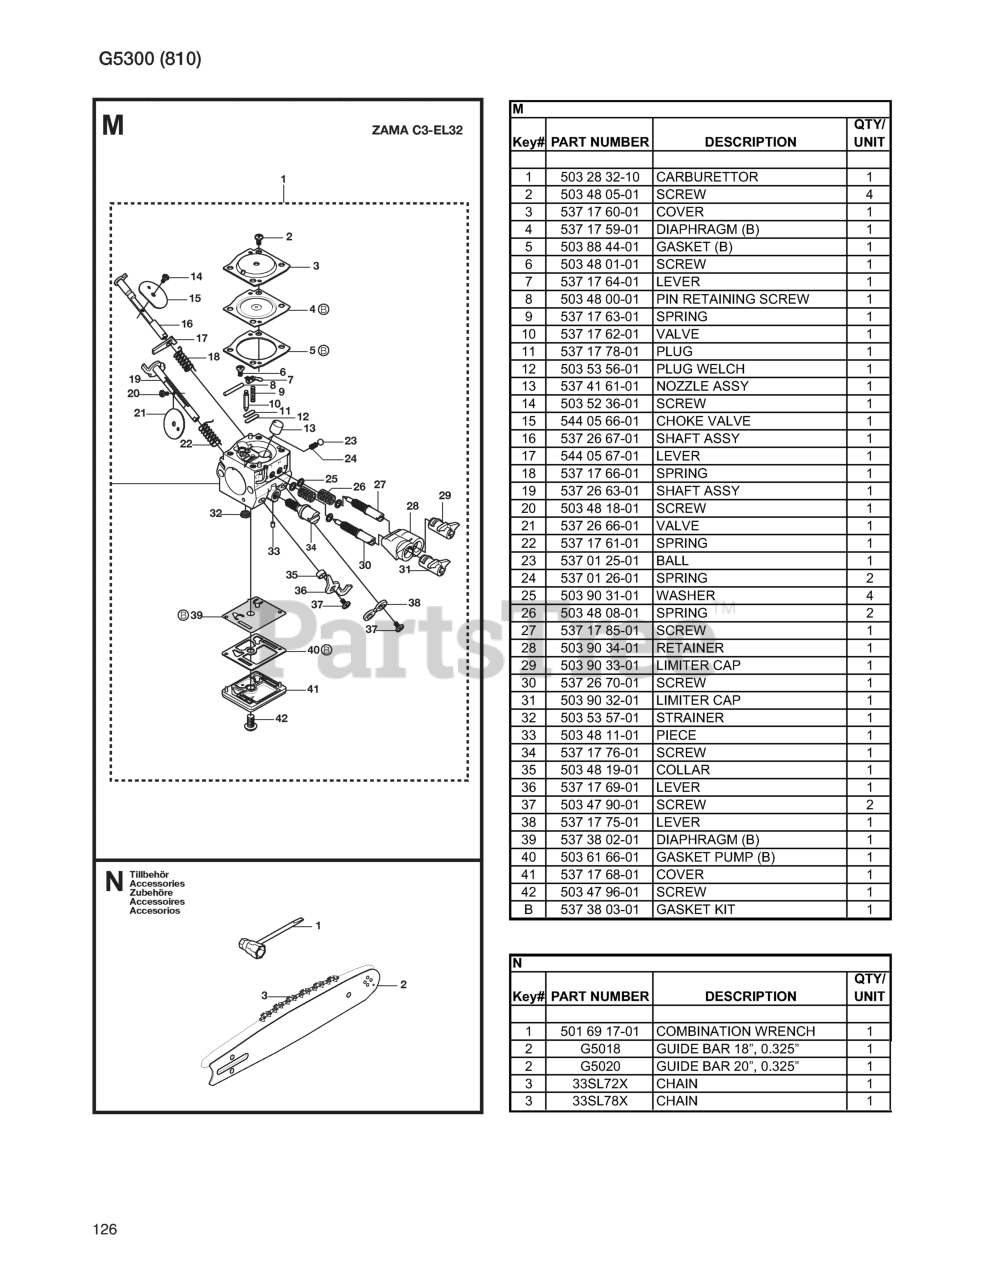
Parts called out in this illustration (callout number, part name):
M1	CARBURETOR
M4	DIAPHRAGM
M8	PIN RETAINING SCREW
M12	PLUG WRENCH
M13	NOZZLE ASSY
M15	CHOKE VALVE
M16	SHAFT ASSY
M19	SHAFT ASSY
M26	SPRING
M28	RETAINER
M29	LIMITER CAP
M31	LIMITER CAP
M32	STRAINER
M39	DIAPHRAGM
M40	GASKET PUMP
B	GASKET KIT
N1	COMBINATION WRENCH
N2	GUIDE BAR
NI	GUIDE BAR
